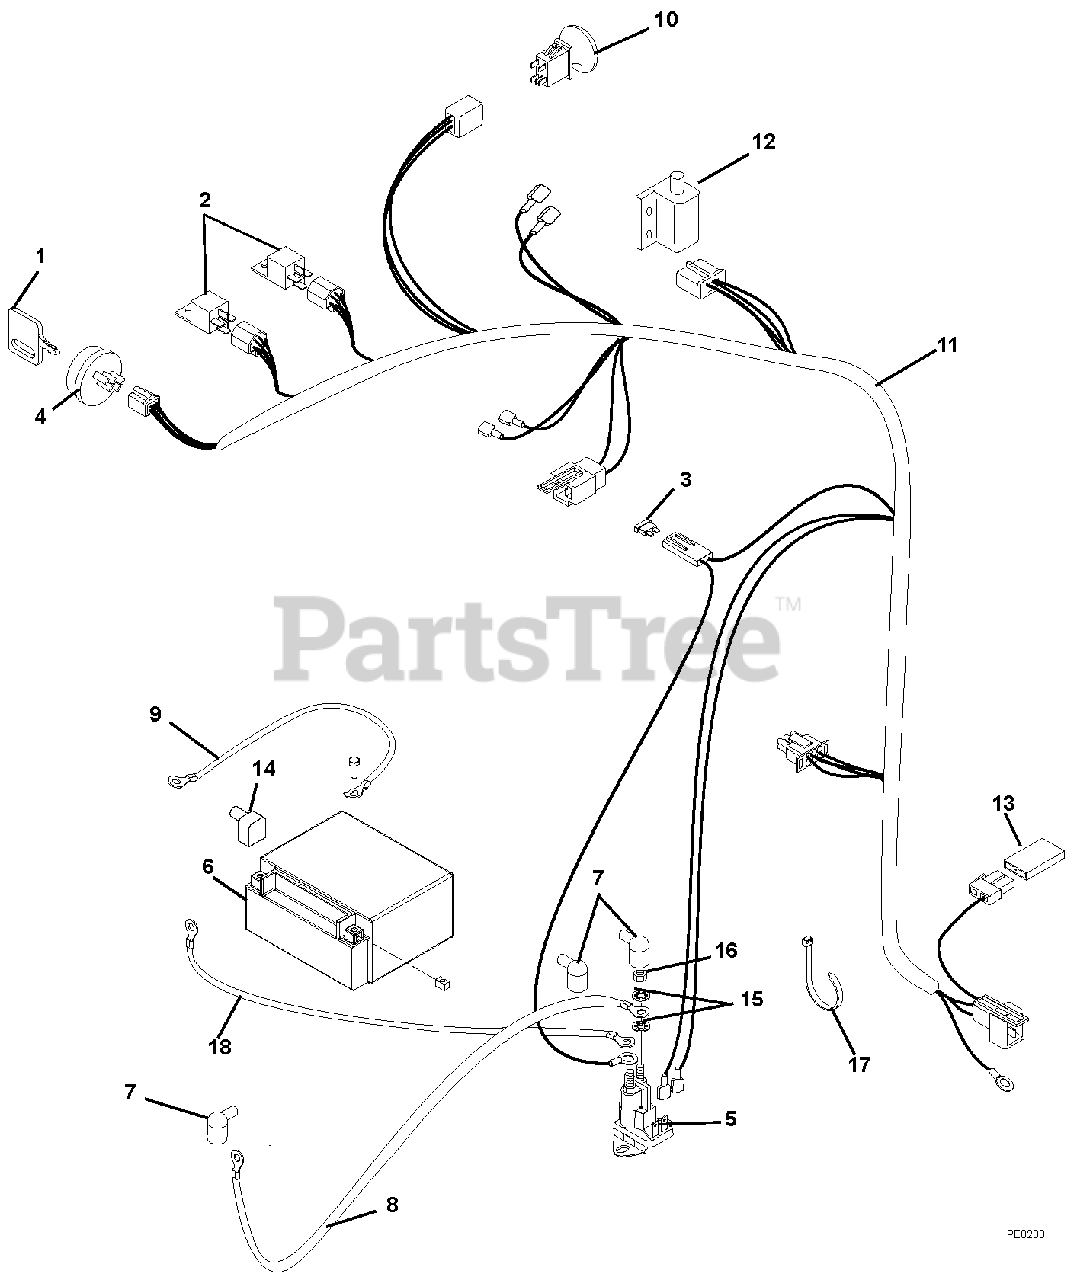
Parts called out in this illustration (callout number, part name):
1	Key with Cap
2	Relay
3	Fuse, 30 AMP
4	Key Switch
5	Solenoid
6	Battery (includes mounting hardware)
7	Boot, Eyelet Terminal
8	Starter Cable
9	Ground Cable
10	Switch, Clutch With Retainer
11	Harness, ZTXL/ZoomXL
12	Switch, Double Pole N.O. / N.O.
13	Diode, Connector Shell
14	Insulator
15	Washer, Locking .31
16	Nut, Jam .31-24
17	Cable Tie
18	Starter Cable
